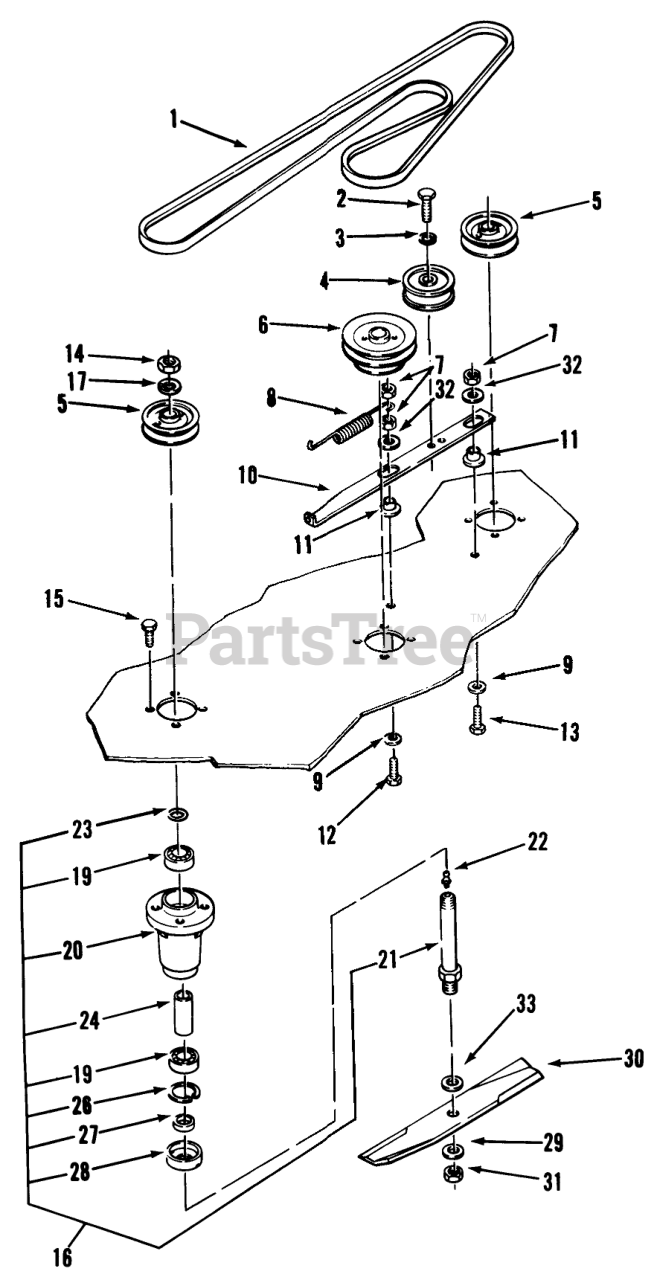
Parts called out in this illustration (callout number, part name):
1	V-BELT
2	Bolt
3	WASHER-LOCK
4	Idler Pulley
5	PULLEY
6	PULLEY
7	NUT-LOCK, NI
8	SPRING-EXTENSION
9	WASHER
10	BAR-IDLER SUPPORT
11	SPACER-BUSHING
12	SCREW-HH
13	Bolt
14	NUT-JAM
15	SCREW-HH
16	Spindle Assembly
17	WASHER-LOCK
19	BEARING-BALL
20	HOUSING-SPINDLE
21	SHAFT-SPINDLE
22	FITTING-GREASE
23	O RING
26	RING-RETAINING
27	SPACER-BLADE
28	CUP-SPINDLE
29	WASHER-FLAT
30	BLADE-14.5IN
31	NUT-JAM
32	WASHER
33	Washer
